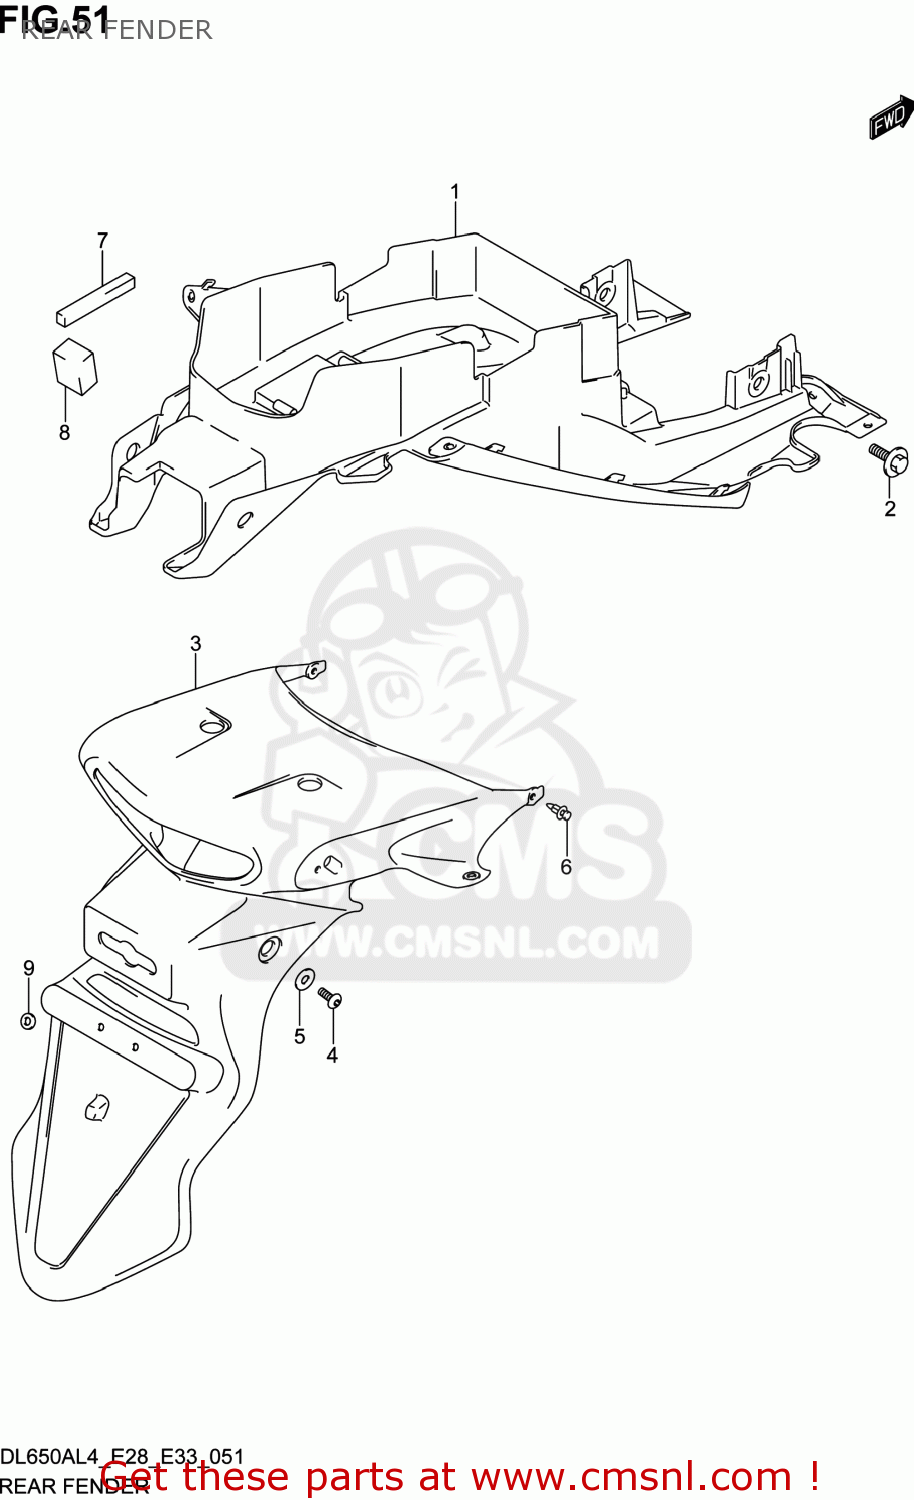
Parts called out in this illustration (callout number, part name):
1	FENDER,RR FR
2	BOLT(6X13)
3	FENDER,RR RR
4	SCREW(6X16)
5	WASHER(6.5X18X1.6)
6	CLIP(BLACK)
7	CUSHION,SEAT TAIL COVER CTR
8	CUSHION,RR FENDER RR
9	WASHER
